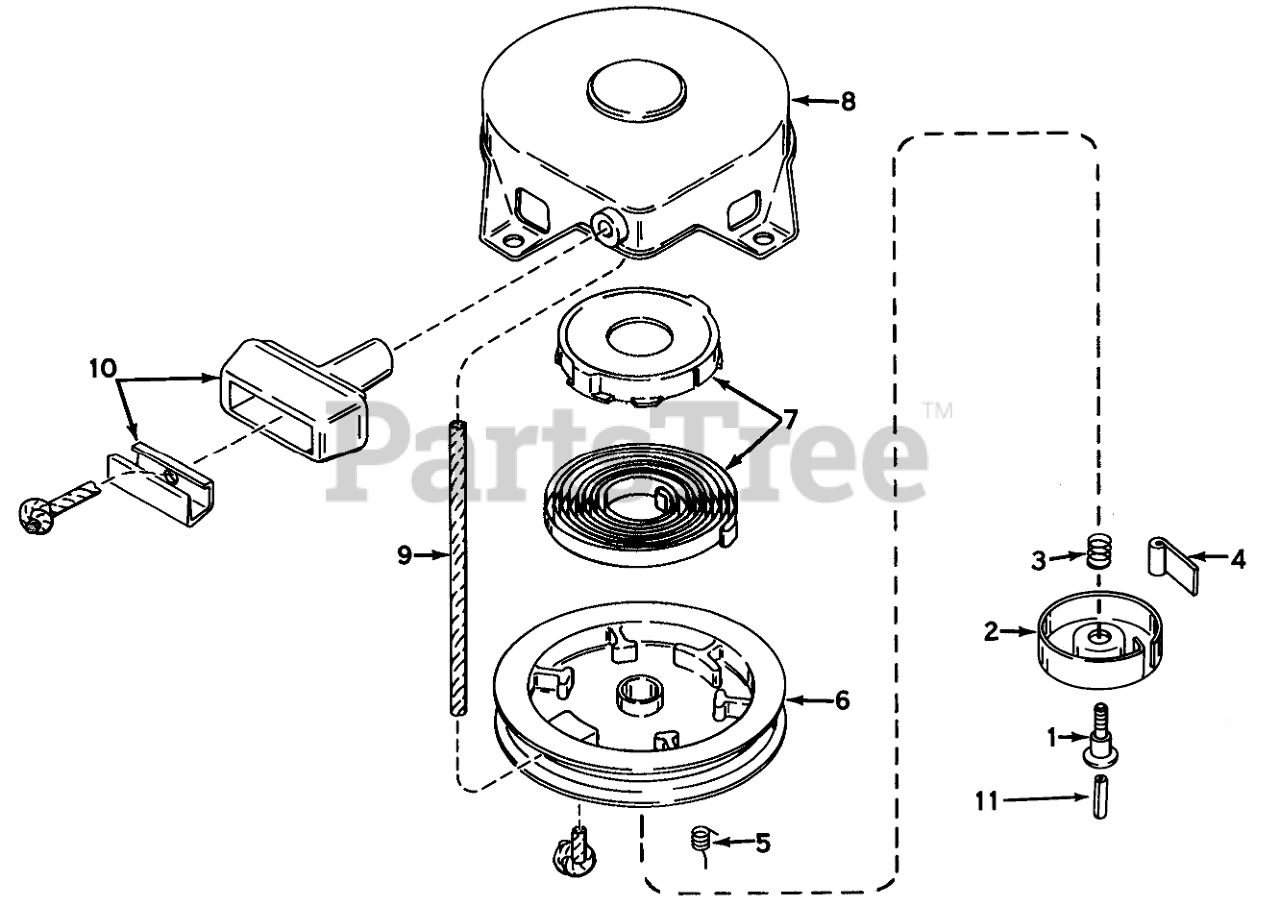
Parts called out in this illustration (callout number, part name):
1	Screw
2	Retainer
3	Spring-Brake
4	Dog-Starter
5	Spring-Dog
7	Spring & Keeper Assy
8	STARTER HOUSING ASSY
9	Rope Starter
10	Assy., Starter
11	Centering
